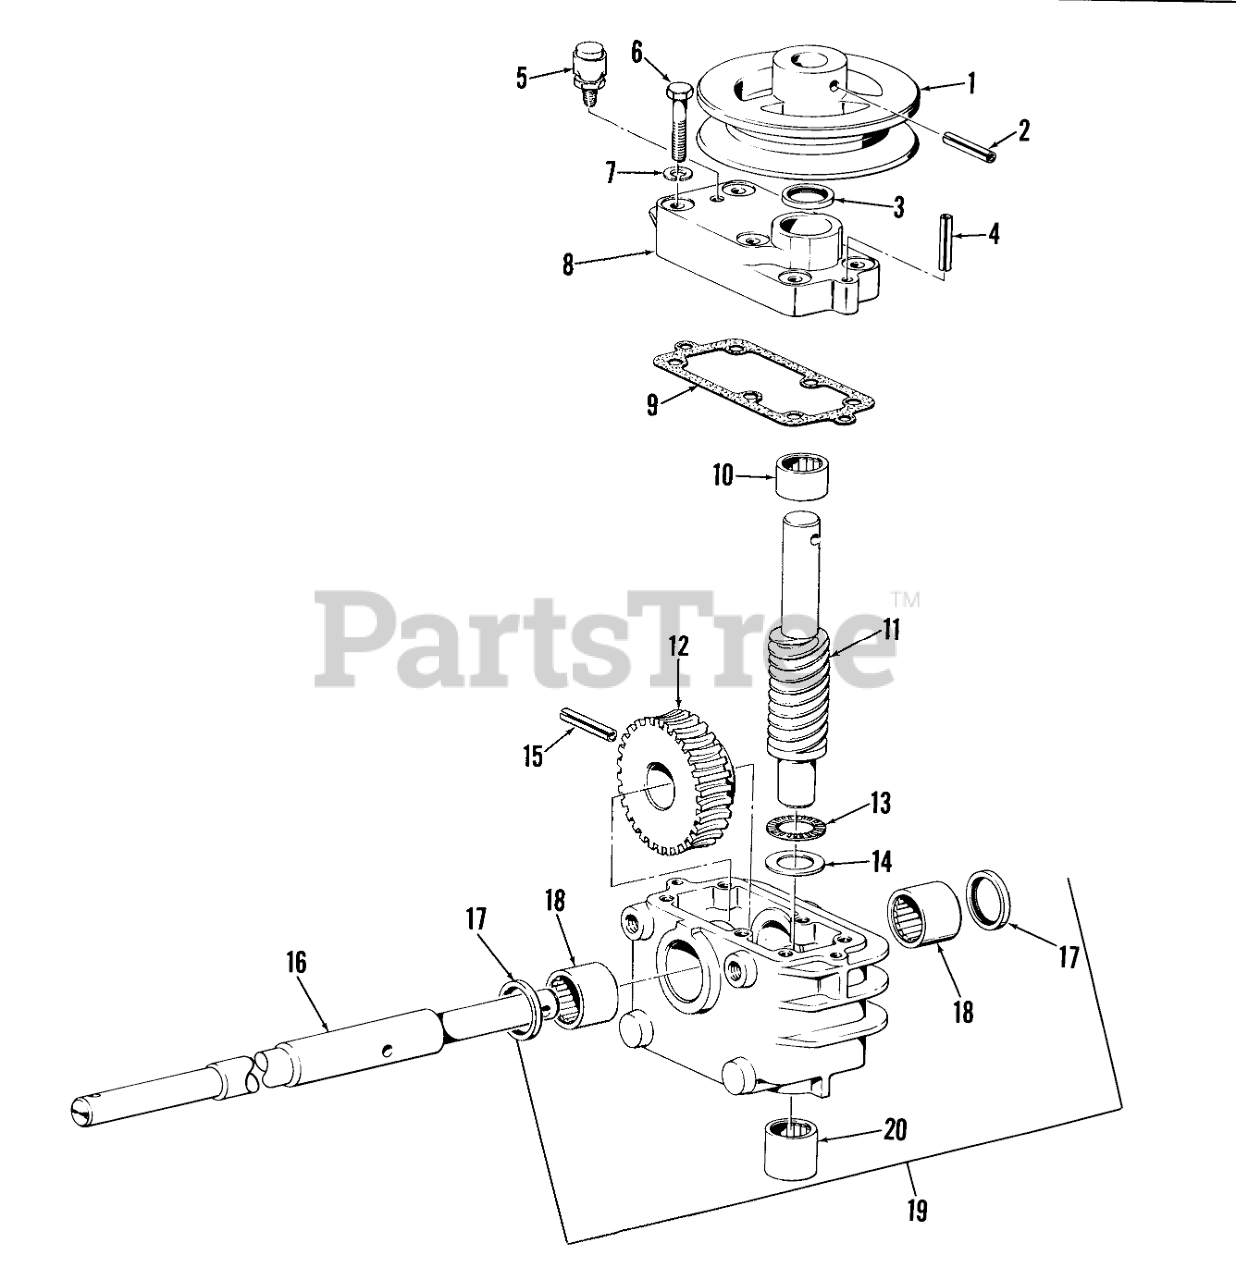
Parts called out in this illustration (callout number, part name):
1	Pulley
2	PIN-ROLL, SLOTTED
3	5/8 X .125 OIL SEAL
4	PIN-ROLL, SLOTTED
5	Vent
6	SCREW-HH
7	WASHER-LOCK
8	Cover, Gear Case
9	Gasket
10	.625 NEEDLE BEARING
11	Shaft, Worm
12	WORM GEAR
13	NEEDLE BRG
14	BEARING-THRUST
15	PIN-ROLL
16	Drive Shaft
16	Drive Shaft 34" H.D.
17	SEAL-OIL
18	BEARING-NEEDLE
19	Gear Case Assy. w/Bearing (Incl. Ref. Nos. 17, 18 & 20)
20	.625 NEEDLE BEARING
